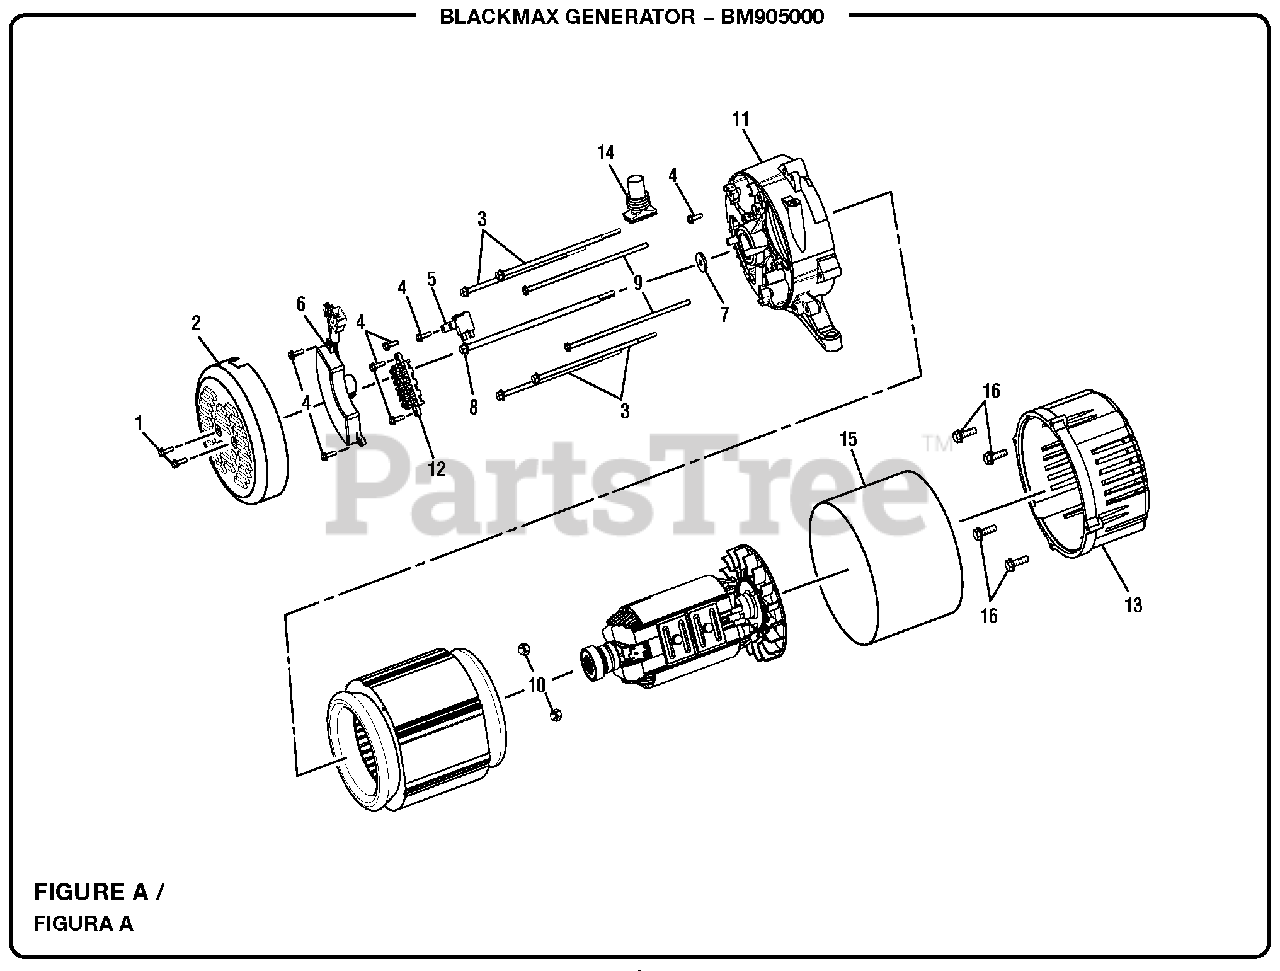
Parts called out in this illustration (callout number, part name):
1	Bolt (M5 x 10 mm, Flange Hex Hd.)
2	Brush Cover
3	Bolt (1/4-20 x 6 in., Hex Hd.)
4	Bolt (M5 x 16 mm, Flange Hex Hd.)
5	Brush Assembly
6	Automatic Voltage Regulator
7	Washer (5/16 in.)
8	Bolt (5/16-24 x 230 mm, Hex. Hd.)
9	Bolt (5/16-24 x 230 mm, Hex. Hd.)
10	Hex Nut (M5)
11	Bearing Support
12	Terminal Block
13	Engine Adapter
14	Rubber Boot
16	Bolt (3/8-16 x 1-1/4 in.)
